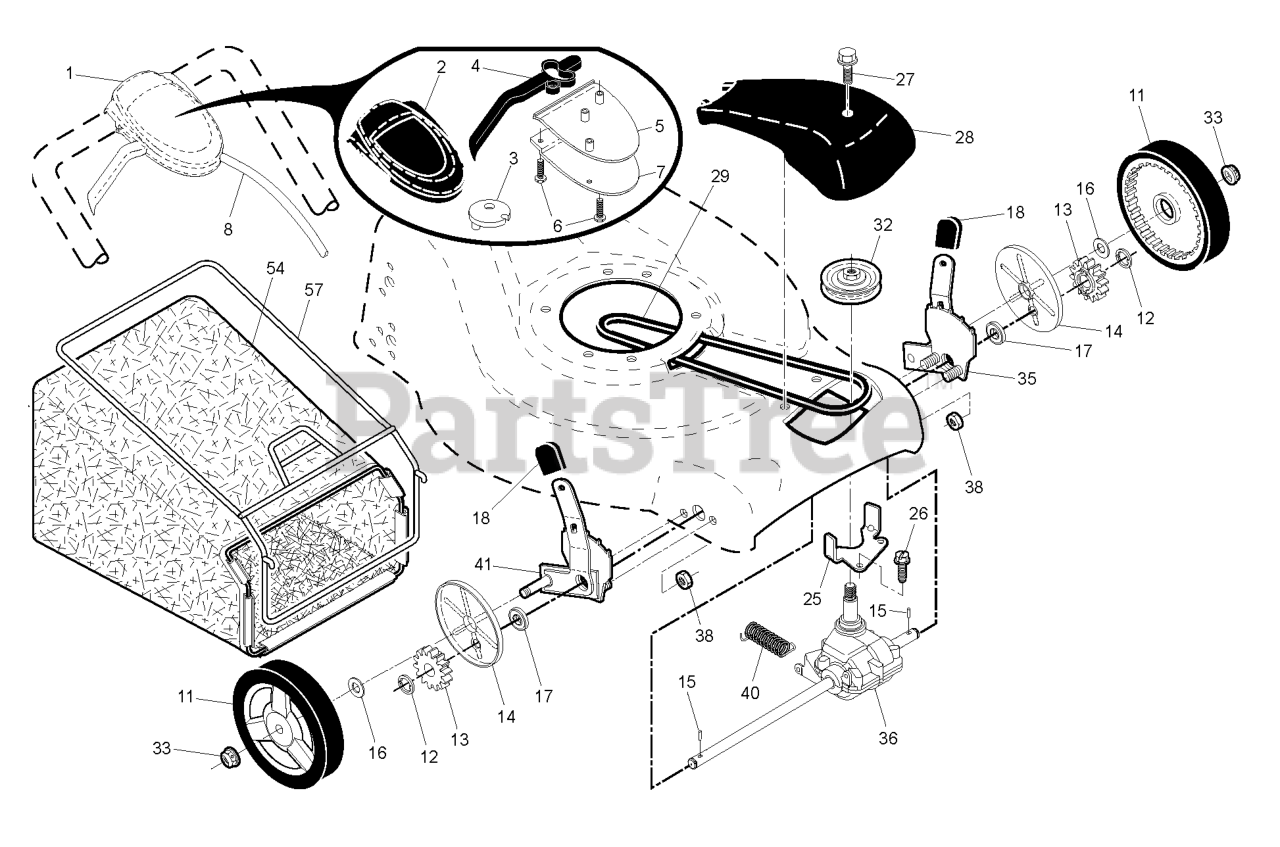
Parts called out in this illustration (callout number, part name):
1	CONTROL.DR.QW.21FGD.BS.GY/BLK
2	COVER TOP AUTO WALK CONTROL
3	PULLEY.CAM.DRIVE.CONTROL.EZ
4	LEVER.BLACK
5	COVER BOTTOM AUTO WLK CONTROL
6	SCREW, PHILLIPS HEAD 10 X 5/8
7	BRACKET.DRIVE.CONTROL.MOUNT.BL
8	CABLE ASSEMBLY, DRIVE
11	WHEEL.8X1.75.H3SPK.RAD3.GY.BU3
12	E-RING 7/16 RE
13	PINION.14.TEETH.FGD
14	COVER.DUST.WHEEL
15	PAWL, DRIVE
16	WASHER FLUT
17	BEARING
18	SELECTOR KNOB
25	BELT KEEPER
27	SCREW, HEX HD TAPPING #10-24 1
28	COVER.DRIVE.21.FWGD.GRAY
29	BELT.DRIVE.FG
32	RP PULLEY.DRIVE.EZ
33	NUT.HEX.FLANGE.3/8-16.LO(3 2)
35	RP KIT, WHEEL ADJUSTER, LH
36	TRANSMISSION.21.FGD.HT.VST
38	LOCKNUT.NYLOC.1/4-20
41	KIT, WHEEL ADJUSTER, RH
54	Grassbag Assembly
57	FRAME.GBAG.21.FWGD
